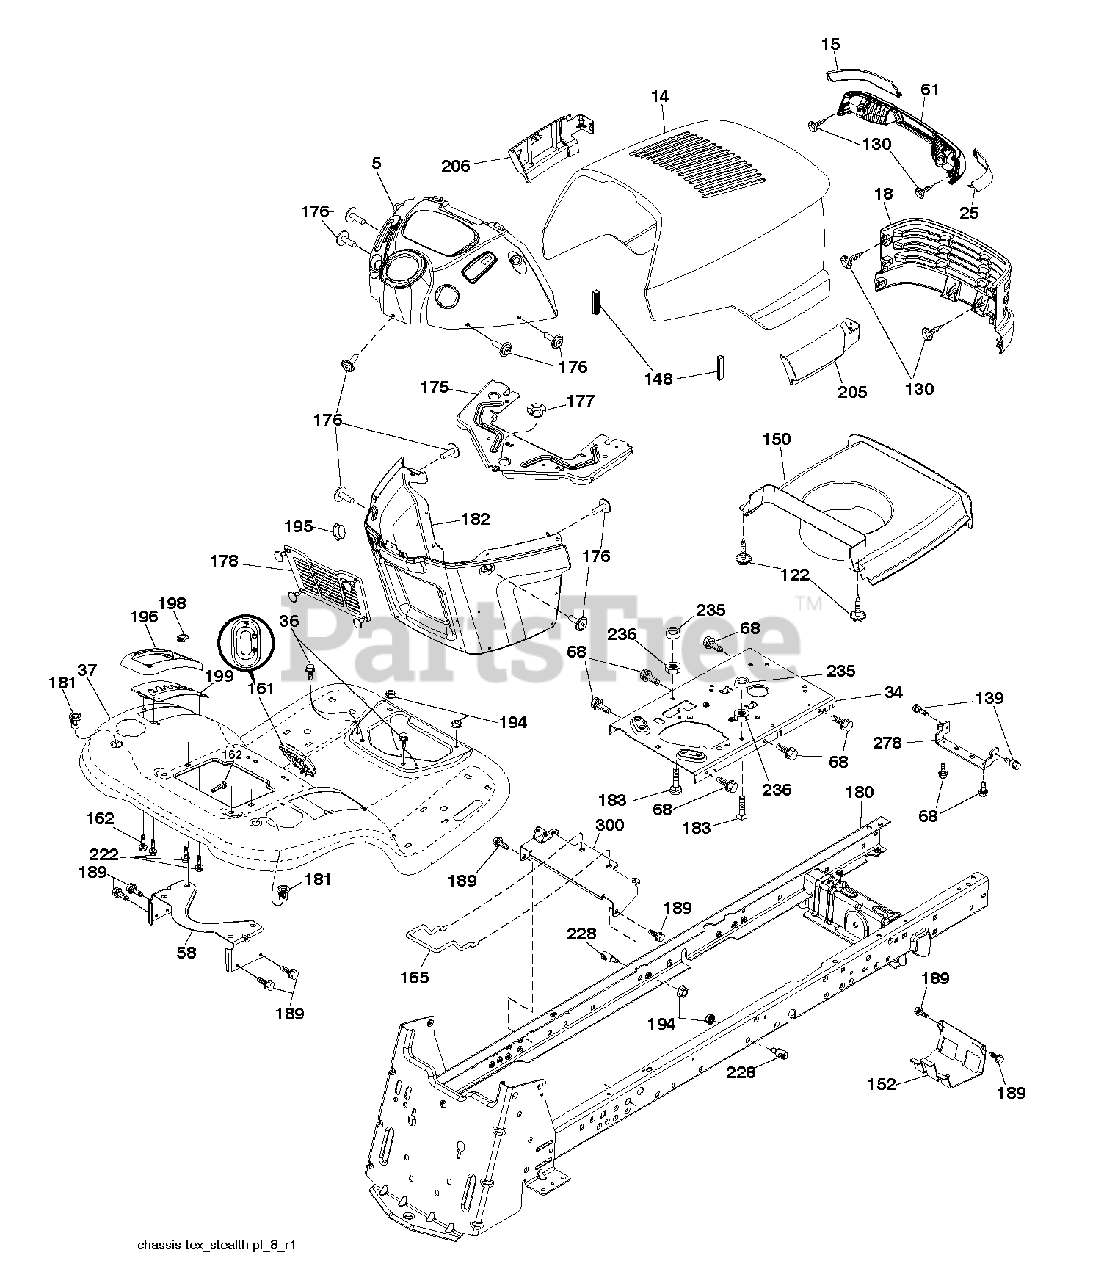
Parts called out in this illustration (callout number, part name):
5	DASH.STEALTH.EL.LIFT.RND.428
15	LENS LH
25	LENS RH
37	FENDER.PNT.TXGT.ERGO.SD.FILL
58	BRKT.SUPPORT.FNDR/TANK
68	SCREW LT
130	SCREW.#10 X 0.750.BOS THREAD
148	EXTRUSION BUMPER
150	DUCT HEAT HOOD
152	SHIELD BROWNING
162	SCREW,HEX
165	SUPPORT.TANK.REAR.B/TE
175	CROSSMEMBER.
176	SCREW.#10-24X5/8.RN.QU
177	BUSHING.STEERING.YT/GT
178	CARGO.ASM.NET.DASH.LOWER
180	CHASSIS
181	FEND/FTRST.PCH.CPH.NFW
182	DASH.LOWER.
183	BOLT.5/16-18X1-1/4 FULL THD
189	SCREW
194	NUT LOCK HEX FLANGE 5/16-18
195	PLUG.HOLE.DASH.LOWER.1
196	CONSOLE.ASM.DECK
199	PLATE.DECK.LIFT.ELECTRIC
205	SKIRT.GRILLE.STEALTH.RH
206	SKIRT.GRILLE.STEALTH.LH
222	SCREW 1/4-20X5/8
228	STUD.FASTNER.W/D.ANTI-
235	SPACER FENDER
236	JAM LOCK NUT
278	BRKT.HOOD/MUFF.STEALTH
300	BRACKET.ASM.LIFT.ELECTRIC
